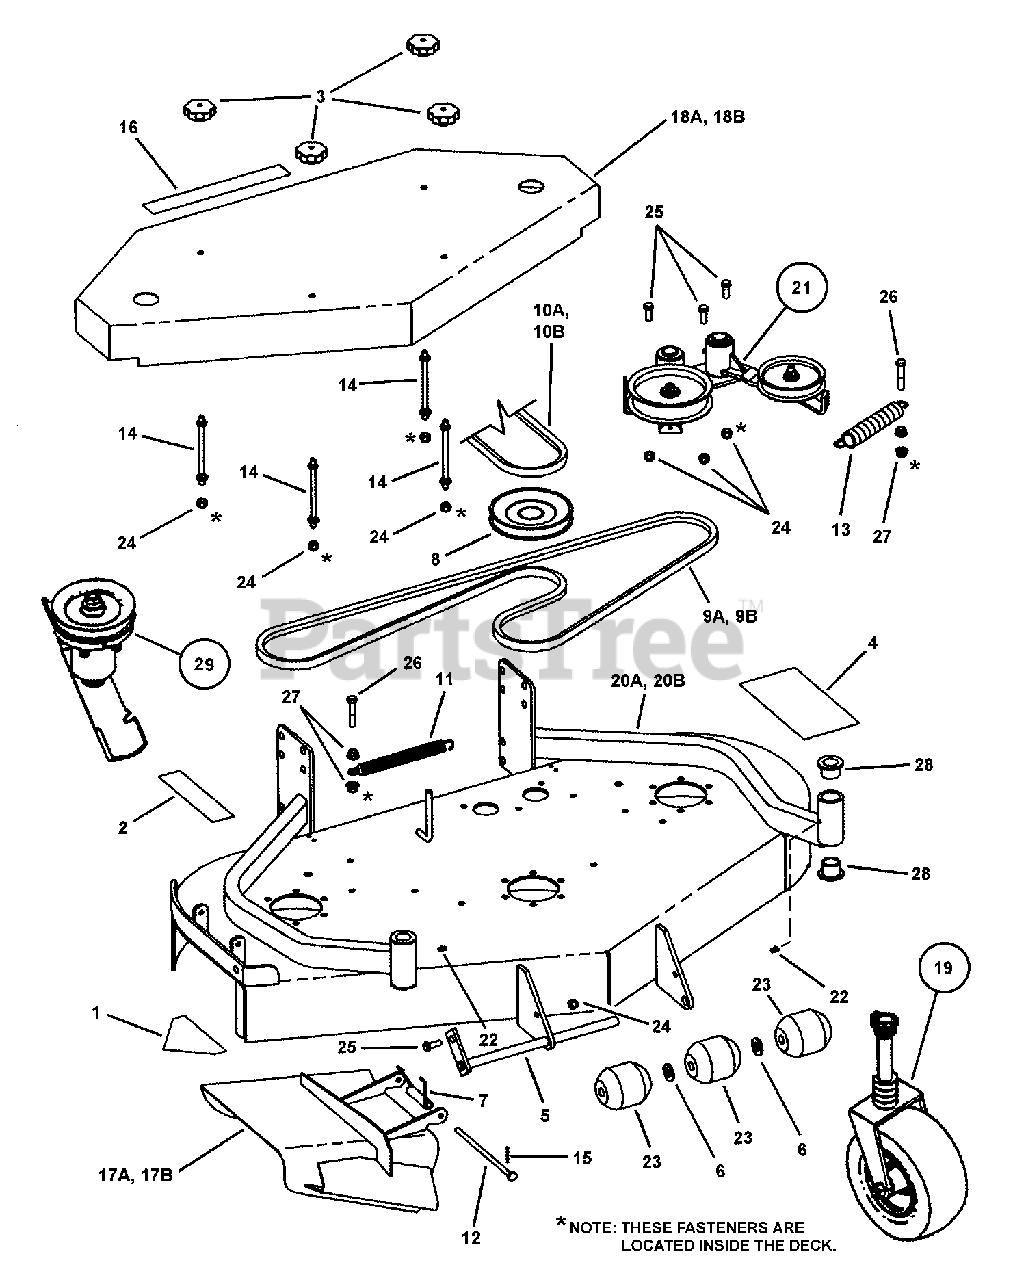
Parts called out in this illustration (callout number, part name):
1	DECAL, Warning (CPSC Cut Finger)
2	DECAL, Danger Guard/Catcher
3	KNOB, Hood (5/16-18 thread)
4	DECAL, Caution- Operator Instruction
5	PIVOT, Roller Pin (Weldment)
6	WASHER, 5/8" Flat
7	SPRING, Chute
8	PULLEY, Driven, 5-3/4" O.D.
9A	* V-BELT, Secondary 48" (113" Long)
9B	* V-BELT, Secondary 52" (120" Long)
10A	* V-BELT, Primary 48" (66" Long)
10B	* V-BELT, Primary 52" (69" Long)
11	SPRING, Extension, Primary Idler
12	HINGE PIN, Chute
13	SPRING, Idler
14	STANDOFF, 4-1/2" Long (5/16-18 thread top; 3/8-16 bottom)
15	COTTER PIN, 3/32 x 1"
16	DECAL, SNAPPER Pro w/Trademark
17A	DEFLECTOR, 48" ANSI Compliant (Weldment)
17B	DEFLECTOR, 52" Euro Chute
18A	COVER, 48" Deck
18B	COVER, 52" Deck
19	ASSEMBLY, Caster Red (Fixed Deck)
20A	ASSEMBLY, 48" Deck (Fixed Height)
20B	ASSEMBLY, 52" Deck (Fixed Height)
21	ASSEMBLY, Idler- 3 Spindle Deck
22	LUBE FITTING, 1/4-28 Straight
23	ROLLER, Low Density Polyethylene
24	NUT, 3/8-16 HEX NYLON LOCK
25	BOLT, 3/8-16 X 1" GD5 CZ
26	BOLT, 3/8-16 X 2, GD5, CZ
27	NUT, 3/8-16 Hex Flange Lock
28	BUSHING, Caster
29	ASSEMBLY, Spindle
